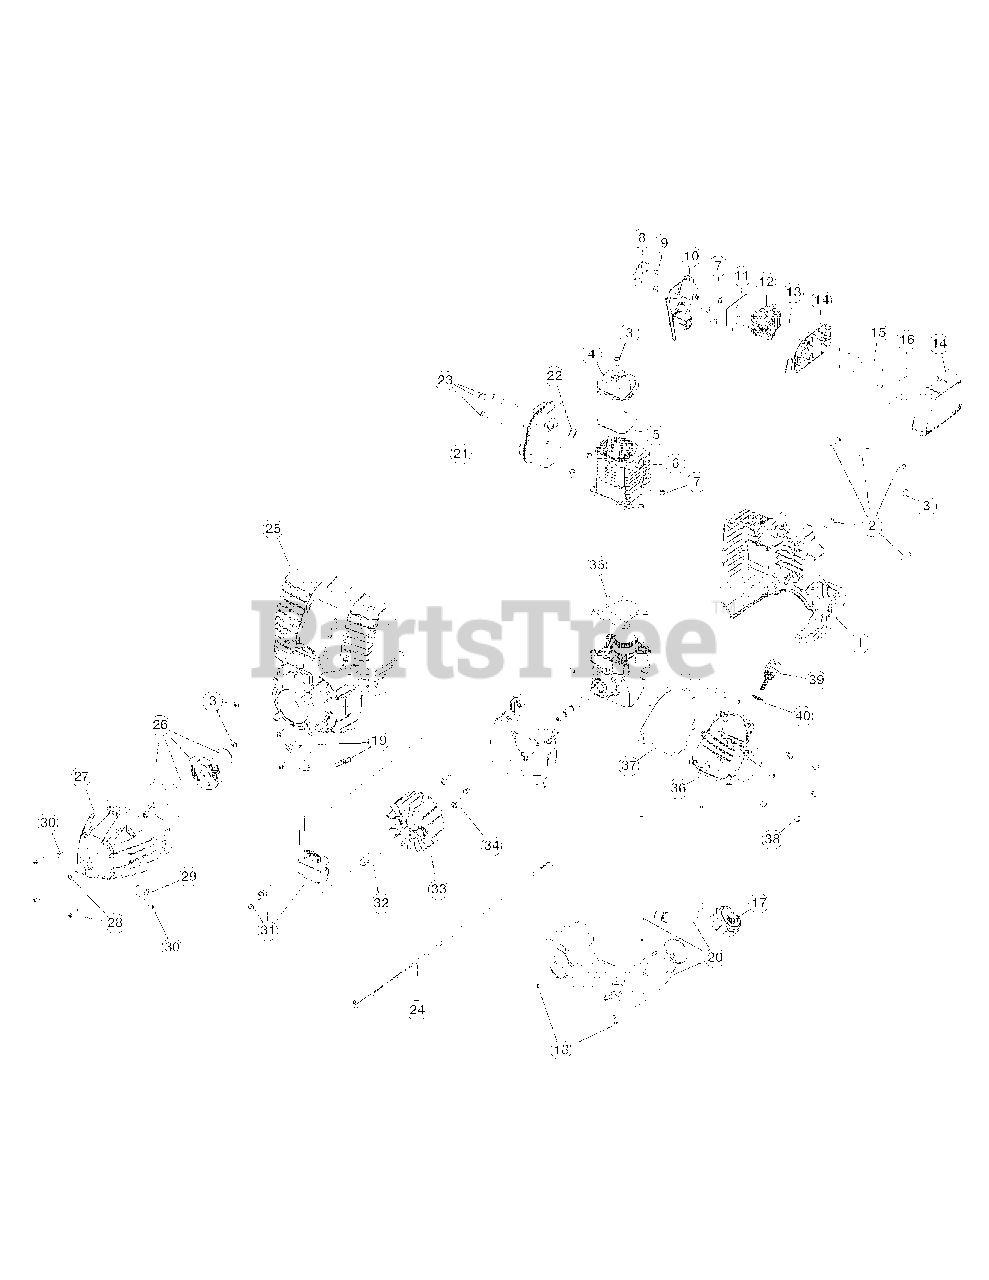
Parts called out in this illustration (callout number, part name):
1	Engine Cover
4	Valve Cover
5	Valve Cover Gasket
6	Cylinder Assembly (Incl. Ref No. 5, 7 & 35)
7	Cylinder Screw
8	Insulator Gasket
10	Insulator (Incl. Ref No. 11)
11	Carburetor Gasket
12	Carburetor w/Primer
13	Carburetor O-Ring
14	Air Filter Cover Assembly (Incl. Ref No. 15 & 16)
15	Air Filter Mounting Screw
16	Air Filter
17	Fuel Cap
19	Clip Nut
20	Fuel Tank Assembly (Incl. Ref No. 17)
21	Muffler Assembly (Incl. Ref No. 22 & 23)
22	Muffler Gasket
23	Muffler Mounting Screw
24	Lead Wire
25	Starter Housing Assembly (Incl. Ref No. 3)
26	Clutch Assembly
27	Clutch Cover Assembly (Incl. Ref No. 28-30)
28	Cover Screw
29	Anti-Rotation Screw
30	Clamping Screw Assembly
31	Module Assembly
32	Spacer
33	Flywheel
34	Shroud Screw
35	Cylinder Gasket
36	Oil Pan (Incl. Ref No. 37 & 38)
37	Oil Pan Gasket
38	Oil Pan Screw
39	Dipstick Assembly (Incl. Ref No. 40)
